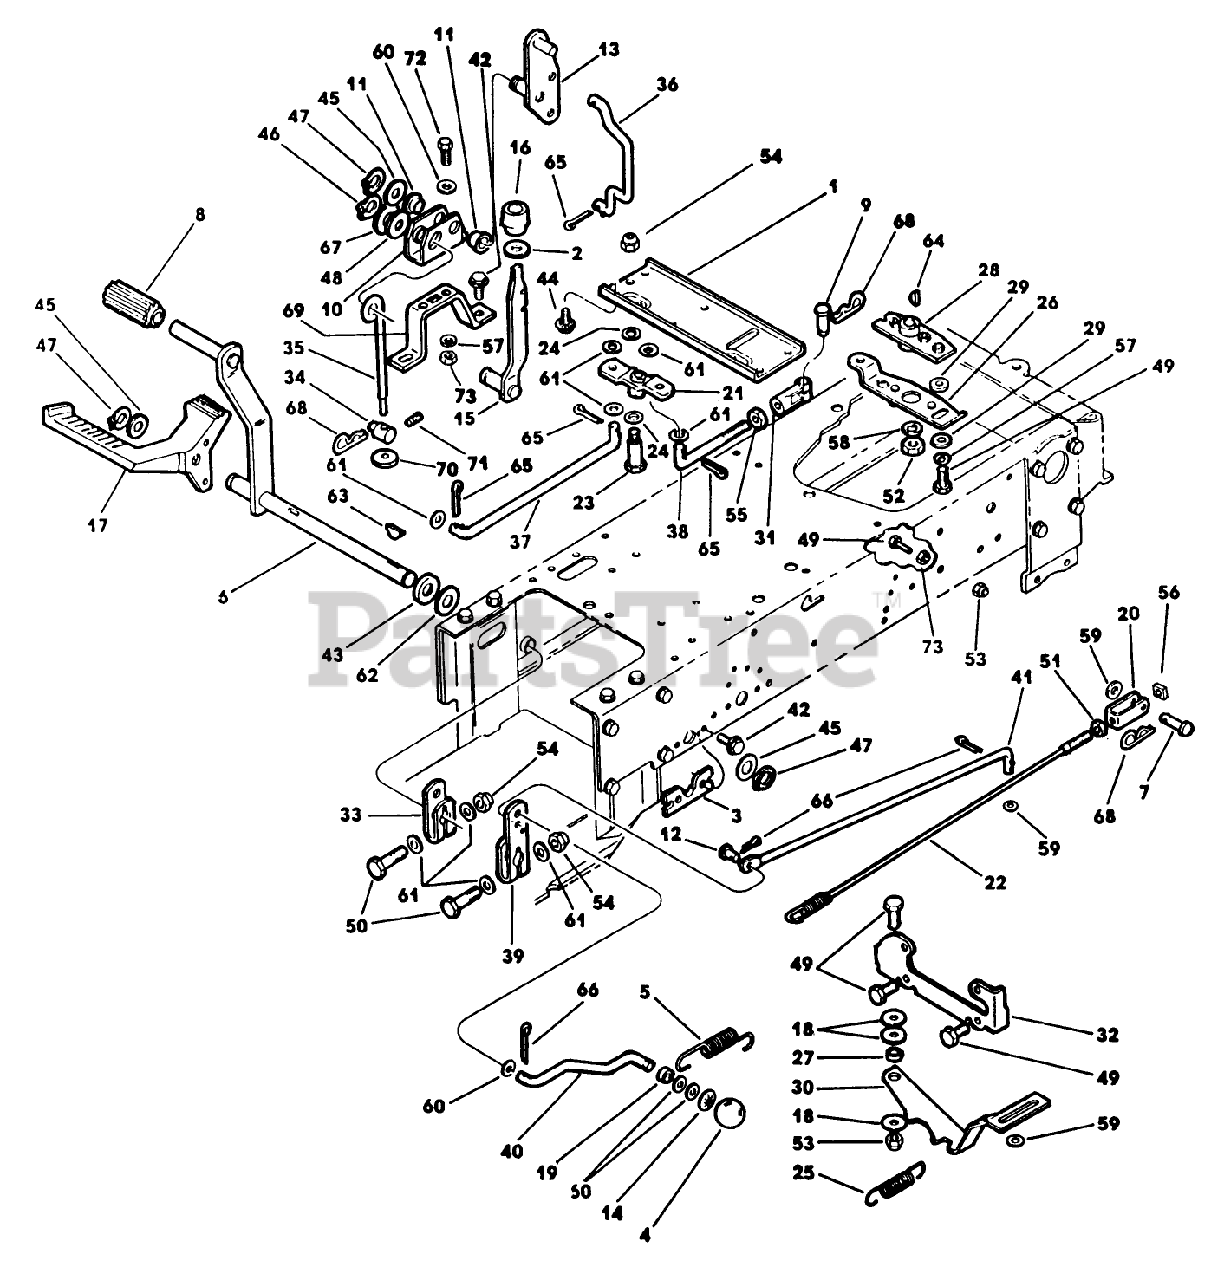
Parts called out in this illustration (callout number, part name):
12	PIN-CLEVIS
15	CRUISE RELEASE AY.
20	CLEVIS
21	BELLCRANK ASSEMBLY *B
22	CABLE AY - BRAKE
24	WASHER - SHIM
25	SPRING - TENSION
28	LEVER ASSEMBLY (12)
32	BRACKET ASSEMBLY
43	WASHER-CUPPED
45	WASHER
46	RING - RETAINING
49	SCREW
51	NUT
53	NUT
54	NUT-LOCKING
55	NUT-HEX
61	WASHER
68	PIN-HAIR
72	SCREW - HEX
73	NUT SS
